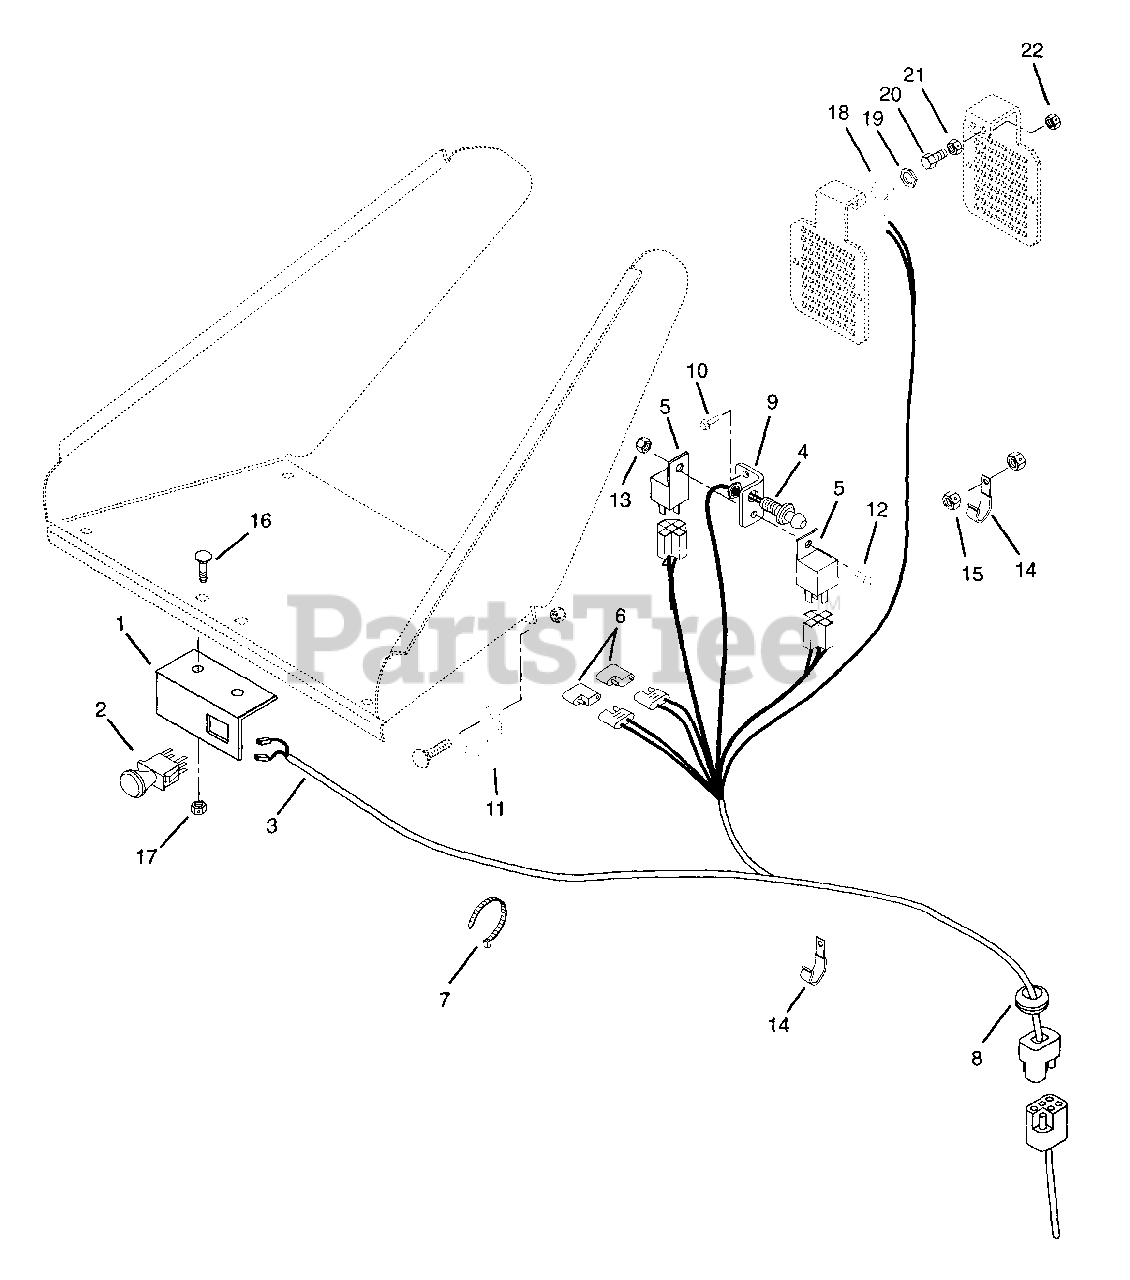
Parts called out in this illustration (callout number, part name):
1	Bracket, Stop Switch
2	Switch, Push/Pull
2	Switch, Emergency Stop
3	Harness, Wiring
4	Switch
5	Relay
6	Diode
7	Tie Wrap
8	Grommet .75 x 1.06 x 1.38
9	Bracket-Switch & Relay
10	Screw, Tapping .25-20 x .50 Hex Washer Head
11	Clamp, Line
12	Screw-Machine 10-24 x .75 Hex Washer Head
13	Nut-Locking-Nylon 10-24 w/Insert
14	J-Clamp
15	Nut-Locking-Center .38-16
16	Bolt-Round Head Square Neck .25-20 x .50 Grade 5
17	Nut-Locking-Center .25-20
18	Switch, Safety
19	Nut, Stamped .56-18
20	Bolt-Hex .31-18 x 1.00 Grade 5
21	Nut-Hex .31-18
22	Nut-Locking-Center .31-18
